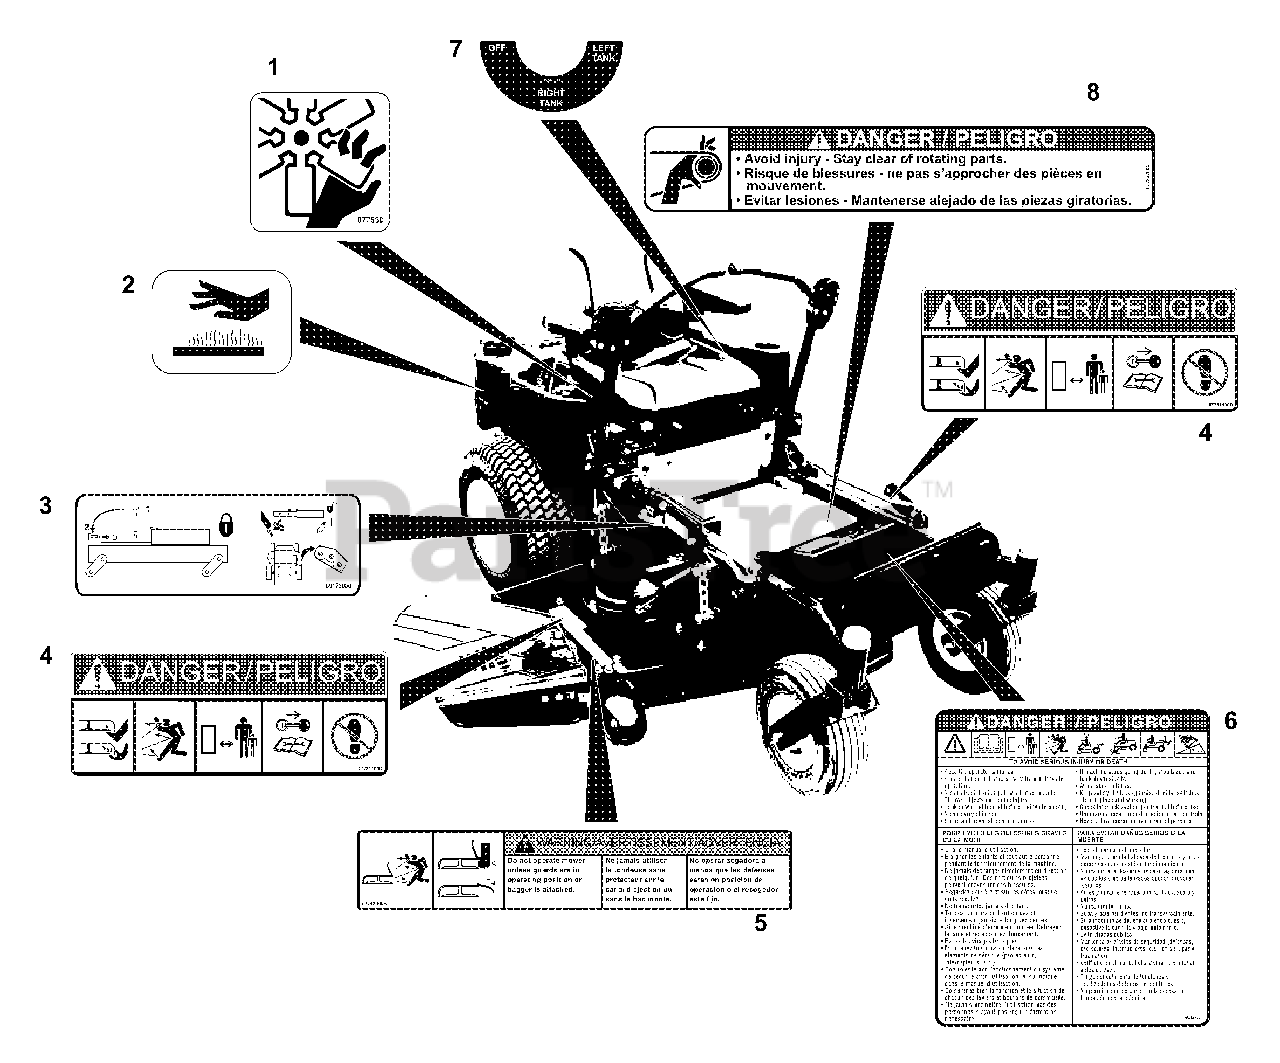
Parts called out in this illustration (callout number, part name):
1	DECAL, DANGER FAN
2	DECAL, HOT SURFACE
3	DECAL, DECK SERVICE
4	DECAL, MOWER PAN DANGER
5	DECAL, WARNING
6	SET-DECAL, COMMON DANGER/FUEL
7	DECAL, FUEL VALVE
8	DECAL- DANGER
